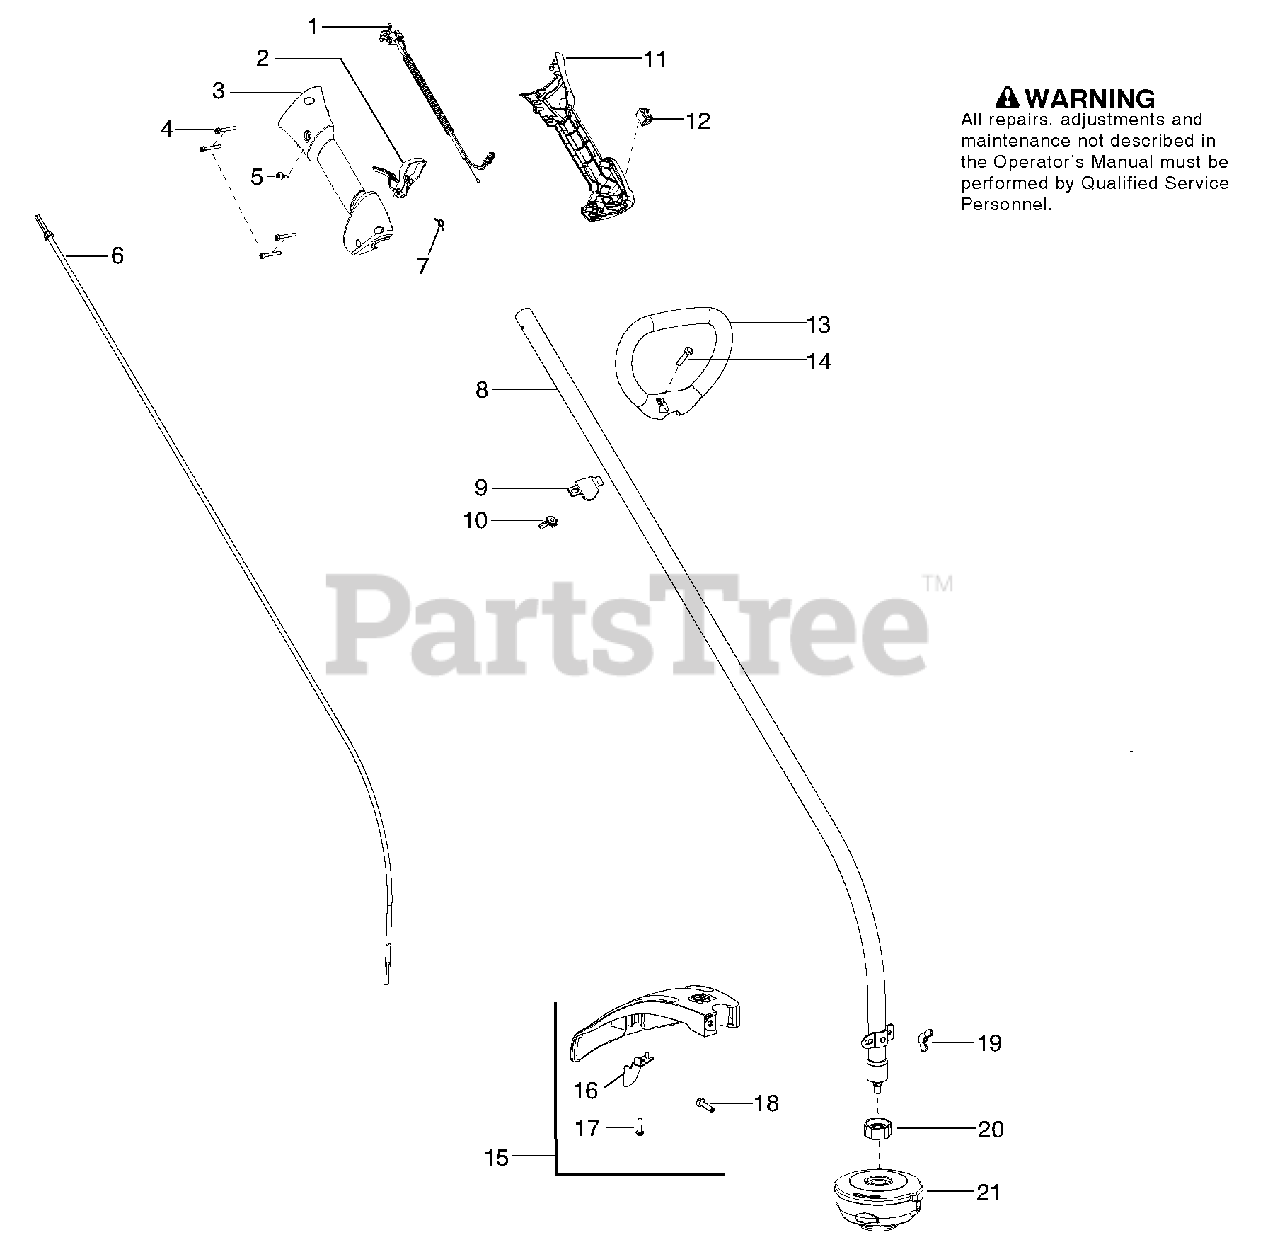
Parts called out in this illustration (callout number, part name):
1	Assy-Cable/Wire Harness
2	Trigger
3	Housing-Throttle (RH)
4	Screw
5	Screw
7	Spring-Trigger
8	Kit-Driveshaft
9	Clamp-Handle
10	Wingnut
11	Housing-Throttle (LH)
12	Kit-Switch
13	Handle-Assist
15	Kit-Shield
16	Kit - Limiter-Line
19	Wingnut
21	Assy-T25 Cutting Head
